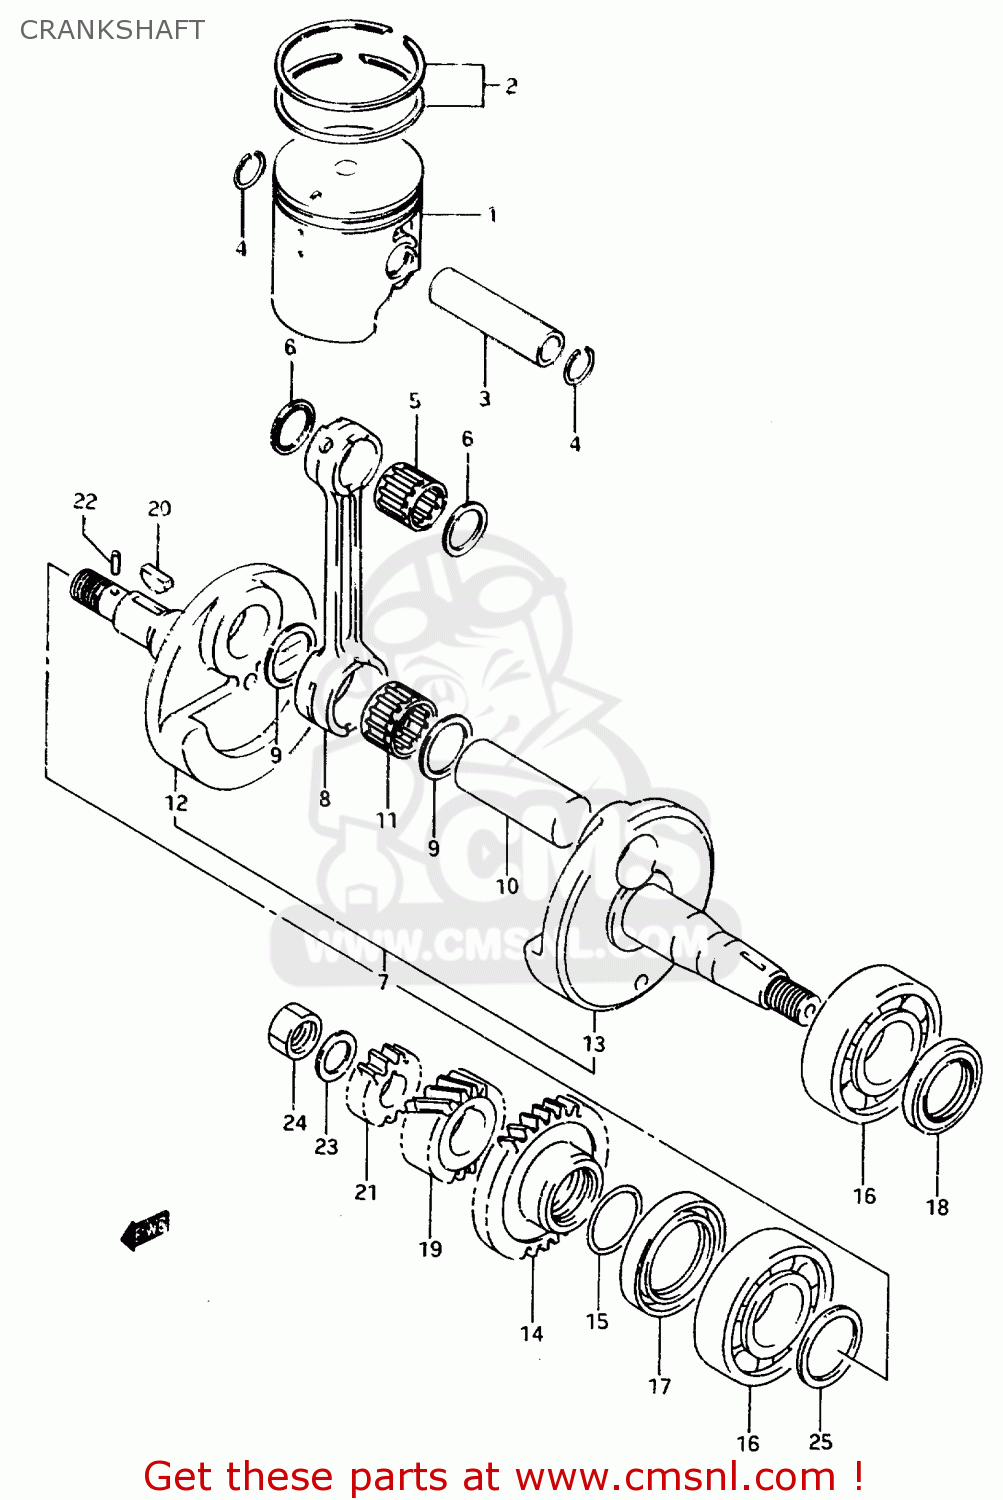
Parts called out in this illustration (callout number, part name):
1	PISTON (OS:0.5)
2	RING SET,PISTON
3	PIN, PISTON
4	RING,SNAP 16MM
5	BEARING(16X20X17.8)
6	WASHER
7	CRANKSHAFT ASSY
8	ROD,CONNECTING
9	WASHER(22X27.5X1.5)
10	PIN,CRANK
11	ROLLER BEARING (22X28X1
12	CRANKSHAFT, RH
13	CRANKSHAFT,L
14	GEAR,CRANK BLANCER DRIVE
15	O RING(D:2.3,ID:24.4)
16	BEARING(25X62X17)
17	SEAL,OIL(36X52X8)
18	SEAL,OIL(25X36X6)
19	GEAR,PRIMARY DRIVE
20	KEY
21	GEAR,WATER PUMP DRIVE
22	PIN
23	WASHER
24	NUT
25	PASTILHA
